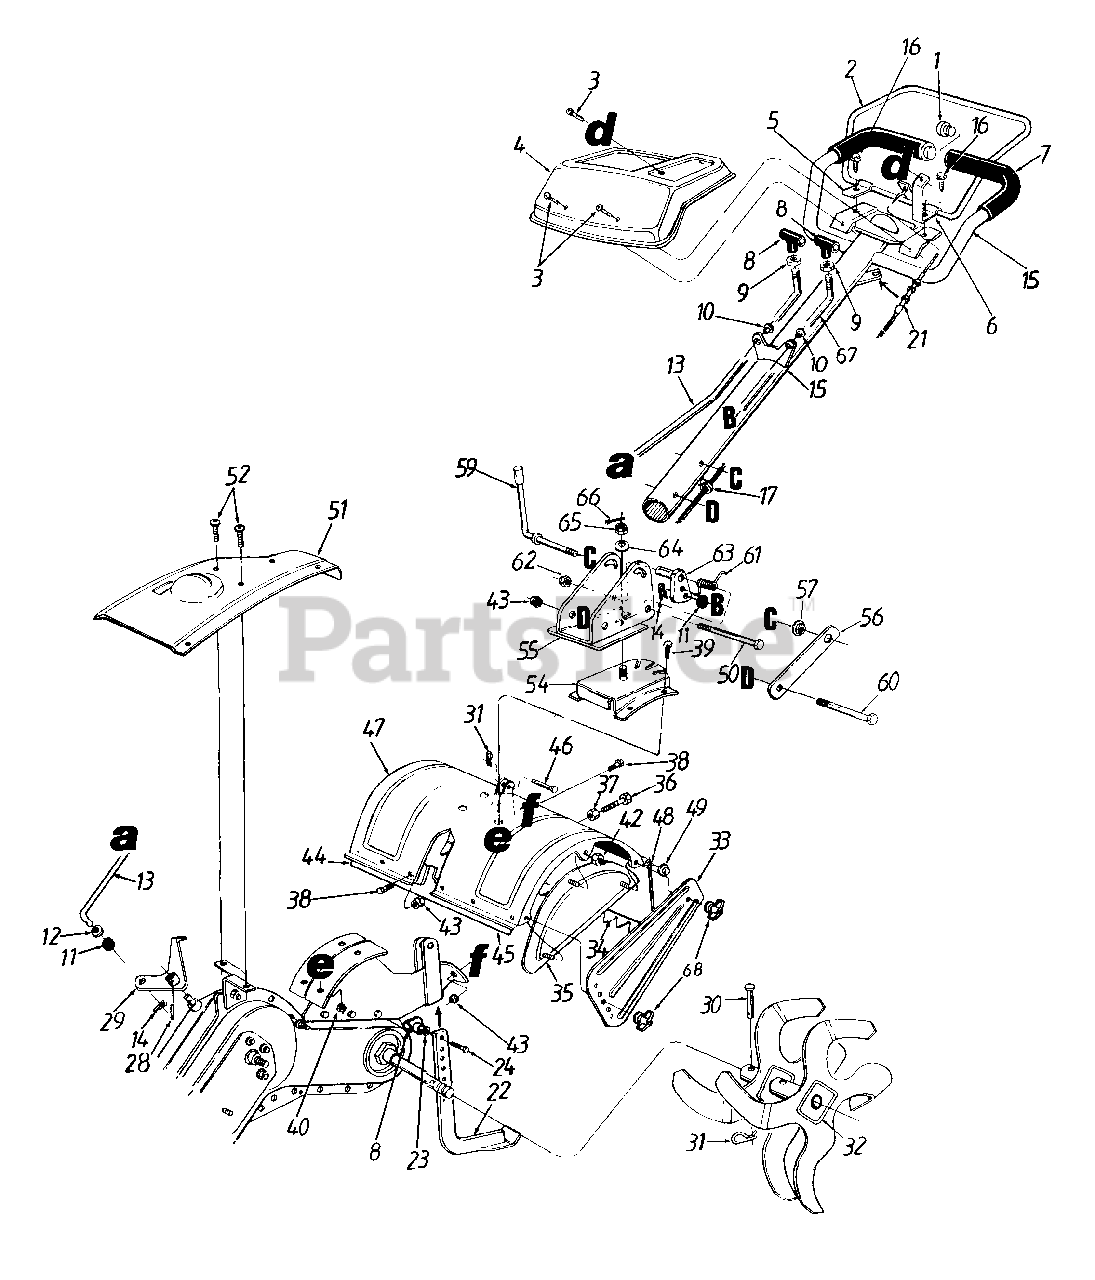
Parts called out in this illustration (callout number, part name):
1	Vinyl End Plug
3	Torx Mach. AB-Tap Scr. 1/4 x .62" Lg.
7	Grip
9	Hex Jam Nut 3/8-16 Thd.
10	Bushing 3/8" I.D.
11	Rubber Washer
12	Fl-Wash. .344" I.D. x .6" O.D.
13	Gear Shift Rod
14	Hairpin Clip
17	Cable Clip
21	Clutch Cable
23	Fl-Wash. 3/8" I.D. x 5/8" O.D.
24	Hex Bolt 3/8-16 x 1" Lg.
28	Spiral Pin 3/16" x 1"
31	Hairpin Clip
36	Hex Cap Bolt 5/16-18 x 1.25" Lg.
37	Hex Nut 5/16-18 Thd.
38	Hex Bolt 5/16-18 x .75" Lg.
39	Carriage Bolt 3/8-16 x 1" Lg.
40	Hex Ins. L-Nut 3/8-16 Thd.
42	Hex Cap L-Nut 5/16-18 Thd.
43	Hex Flange Top L-Nut 5/16-18 Thd.
46	Clevis Pin .375" Dia.
49	Cap Speed Nut
50	Hex Bolt 3/8-16 x 3" Lg.
52	Torx Mach. AB-Tap Scr. 1/4 x .6"
57	Hex Flange Nut 3/8-24 Thd.
59	Handle Adjustment Crank
60	Hex Bolt 5/16-18 x 3" Lg.
61	Torsion Spring
62	Hex L-Nut 3/8-16 Thd.
63	Handle Swing Link
64	Bell-Wash. 5/8" I.D.
65	Hex Slotted Nut 5/8-18 Thd.
66	Cotter Pin 1/8" x 1-5/8"
67	Handle Adjustment Rod
68	Knob 5/16-18 Thd.
